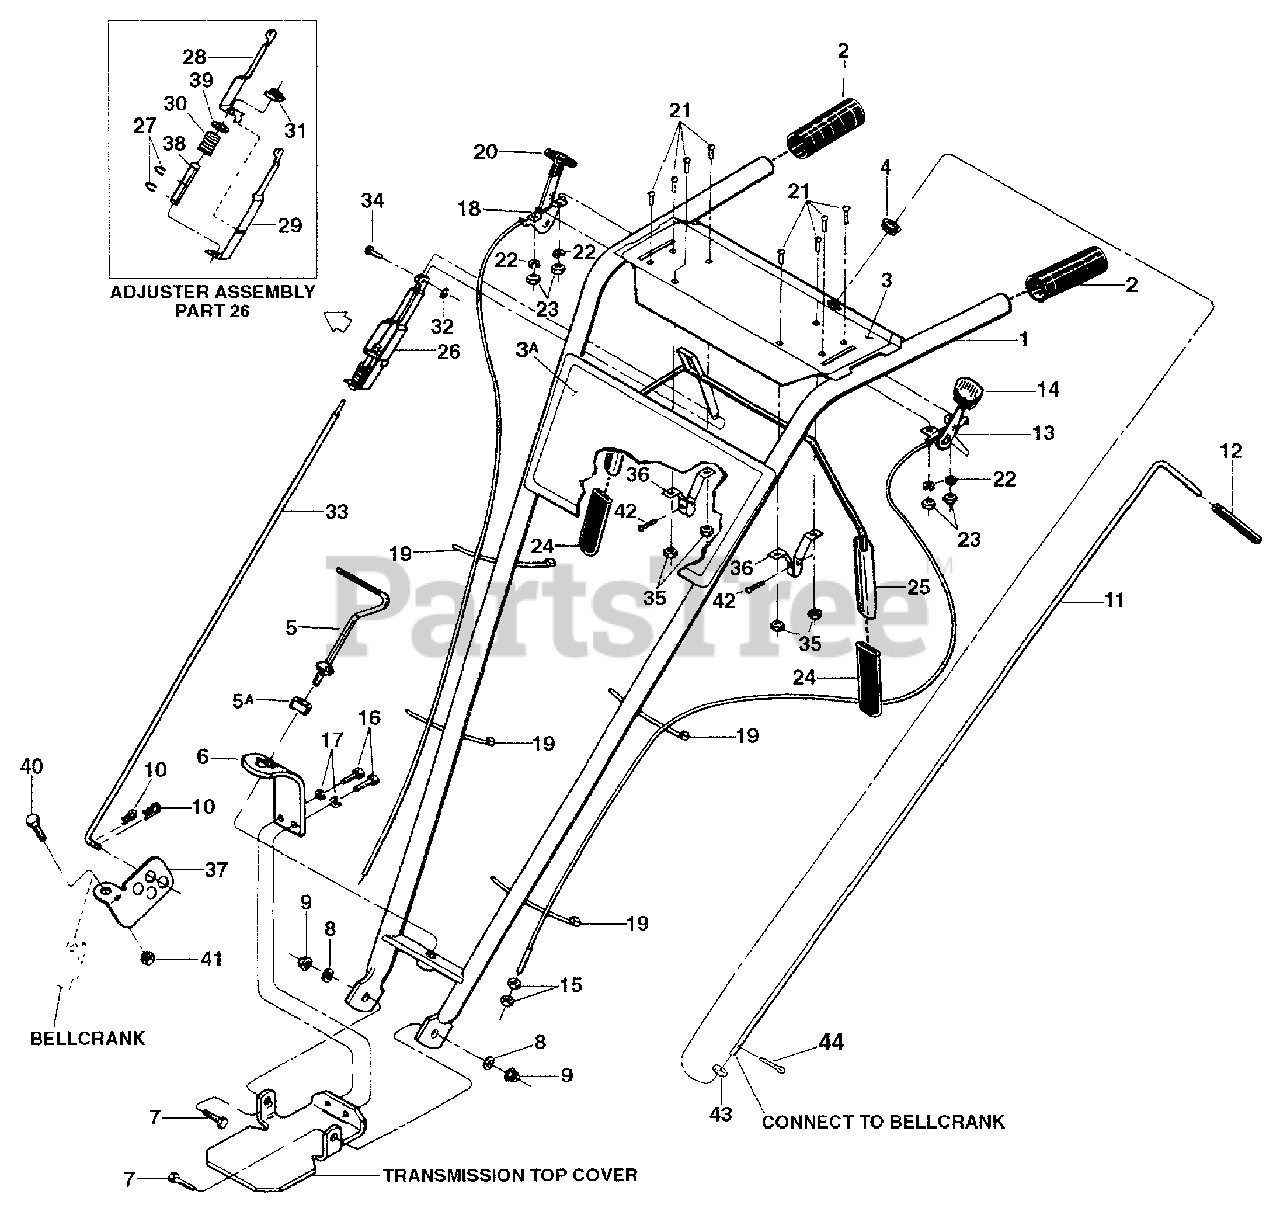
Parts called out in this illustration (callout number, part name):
1	Handlebars
2	Grip-handlebars
3	Decal-for operator control panel
3A	Decal- Logo
4	Grommet-plastic (part of operator control panel)
5	Handle, height adjustment
5A	Washer-keyed
6	Bracket-handlebar height adjust
7	Screw-hex hd., 3/8-16 x 1
8	Washer-plain (flat) 3/8, S.A.E.
9	Locknut-hex, 3/8-16
10	Hair Pin Cotter
11	Reverse Clutch Lever-complete
12	Grip-reverse clutch lever
13	Wheel Gear Control & Cable Assy.
14	Knob-wheel gear control lever
15	Nut-hex, 5/16-24, wheel gear cable adjustment
16	Screw-hex hd., 3/8-16 x 3/4
17	Lockwasher-3/8
18	Engine Throttle Control & Cable
19	Ties-plastic
20	Knob-throttle control lever
21	Screw-round hd, No. 10-32 x 1/2
22	Lockwasher-No. 10
23	Nut-hex, No. 10-32
24	Grip-paddle
25	Bail-forward clutch control
26	Adjuster Assembly
27	Klip Ring
28	Adjuster, Right Side
29	Adjuster, Left Side
30	Spring-Adjuster
31	Nut-rectangular
32	Klip Ring
33	Rod-forward clutch
34	Pin-Clevis
35	Sems Nut
36	Bracket-bail support
37	Swivel
38	Bushing
39	Washer
40	Screw-hex hd., 1/4-20 x 3/4
41	Nut-1/4-20
42	Screw-flanged hex hd, self-tapping, 1/4-20 x 1/2
43	Washer-flat, 5/16"
44	Pin - cotter
